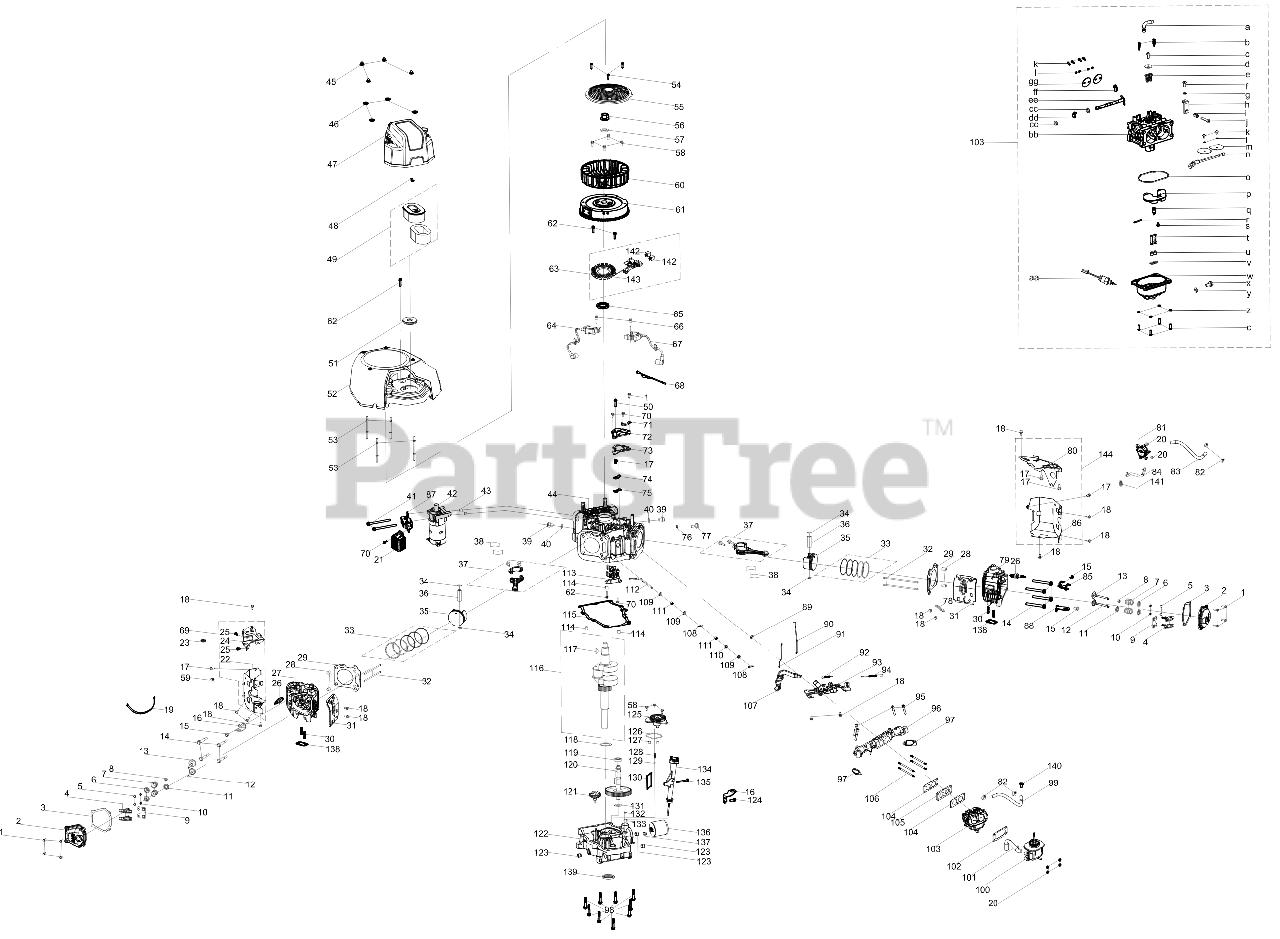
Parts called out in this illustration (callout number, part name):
1	BOLT M6 x 22
2	VALVE COVER
3	VALVE COVER GASKET
4	ROCKER ARM ASSEMBLY
5	EXHAUST VALVE ADJUSTER
6	VALVE SPRING SEAT
7	VALVE SPRING
8	INTAKE VALVE SEAL
9	PUSH ROD GUIDE
10	VALVE CAP
11	VALVE SPRING RETAINER
12	EXHAUST VALVE
13	INTAKE VALVE
14	HEX HEAD BOLT - M10X1.25X87
15	HEX HEAD BOLT M8X16
16	LIFT HOOK BRACKET - LH
17	BOLT M6-1 x 10 GR8.8
18	BOLT M6-1 x 12 GR8.8
19	CABLE TIE - 3 x 150
21	REGULATOR ASSEMBLY
22	CYLINDER HEAD BAFFLE
23	HEAT SHIELD GROMMET
24	FLYWHEEL SHROUD - LH
25	HEX HEAD SCREW M6X10
26	SPARK PLUG
27	CYLINDER HEAD - LH
29	CYLINDER HEAD GASKET
30	STUD M8 x 36
33	PISTON RIN SET
34	PISTON PIN SNAP RING
35	PISTON ASSEMBLY
36	PISTON PIN
37	CONNECTING ROD
38	CONNETING ROS BEARING
39	HEX HEAD BOLT M14-1.5X1.5
40	FLAT WASHER 14X1.5X22
41	HEX HEAD BOLT M8X110
42	ELECTRIC STARTER
45	ACORN NUT
47	AIR FILTER COVER ASSEMBLY
49	AIR FILTER ELEMENT
50	BOLT-M6-1 x 28 GR8.8
52	BLOWER HOUSING
53	STUD - M6-1.0X69.8X117
54	BOLT 5.5 x 25
55	DEBRIS SHIELD
56	NUT M20 x 1.5
57	WASHER 20.5 x 5 x 40
58	BOLT M6-1 x 18 GR8.8
59	PLASTIC SUPPORT CLAMP
60	COOLING FAN
62	BOLT M6-1 x 25 GR8.8
63	CHARGING COIL
64	IGNITION MODULE (LH)
65	OIL SEAL 38 x 58 x 8
66	BOLT-M6-1 x 30 GR8.8
67	IGNITION MODULE (RH)
68	WIRE HARNESS
69	SHROUD ASSEMBLY (LH)
70	BOLT M6 x 16
71	FLYWHEEL GUARD BRACKET
72	BEATHER COVER
73	BREATHER COVER GASKET
74	BREATHER REED BRACKET
75	BREATHER REED ASSEMBLY
76	WASHER 20.5X1.5X18
77	HEX HEAD BOLT M10X1X10
79	CYLINDER HEAD - RH
80	SHROUD (RH)
81	FUEL PUMP
82	HOSE CLAMP
83	FUEL HOSE
85	MOUNTING BRACKET
86	CYLINDER HEAD BAFFLE
87	STARTER RELAY SUPPORT
88	REAR LIFT BRACKET
89	CHOKE LINKAGE LOCK CLAMP
90	THROTTLE LINKAGE
91	CHOKE LEVER
92	GOVERNOR SPRING
93	GOVERNOR GEAR BRACKET ASSEMBLY
94	GOVERNOR SPRING
95	SCREW - M8X50
96	INTAKE MANIFOLD
97	INTAKE MANIFOLD GASKET 9Q78
98	HEX HEAD FLANGE BOLT M8X48
99	FUEL LINE 6.3 x 12.5 x 470
100	INTAKE MANIFOLD
101	BREATHER HOSE
102	AIR FILTER HOUSING GASKET
103	CARBURETOR
104	CARBURETOR GASKET
105	INSULATOR
106	STUD M6-1 x 105
107	GOVERNOR LEVER
108	GOVERNOR SHAFT CLIP
109	FLAT WASHER 8.5X15.8X2
110	GOVERNOR SEAL
111	NEEDLE BEARING 8X12X10
112	GOVERNOR ARM ROD
113	ROACKER ARM
115	CRANKCASE GASKET
116	CRANKSHAFT ASSEMBLY
117	FLYWHEEL KEY
118	WASHER - 38.5X1.0X54
119	CAMSHAFT BEARING
120	CAMSHAFT ASSEMBLY
121	GOVERNOR GEAR
122	CRANKCASE COVER
123	ENGINE PLUG 3/8 NPT
124	HEX HEAD SCREW M8X16
125	OIL PUMP ASSEMBLY
126	OIL PUMP GASKET
127	DOWEL PIN
128	OIL PUMP SPRING
129	OIL PUMP STEEL BALL
130	OIL PUMP SCREEN
131	THRUST WASHER 17.4X25.9X1.0
132	O-RING 13.2X2.65
133	CRANKCASE OIL PASSAGE PIN
134	DIPSTICK ASSEMBLY
135	SCREW M6-1:50:CL5.
136	ENGINE OIL FILTER
137	SCREW JOINT OIL FILTER ADAPTER
138	EXHAUST GASKET
139	OIL SEAL 38 x 58 x 8
143	CHARGING COIL
144	SHROUD ASSEMBLY (RH)
